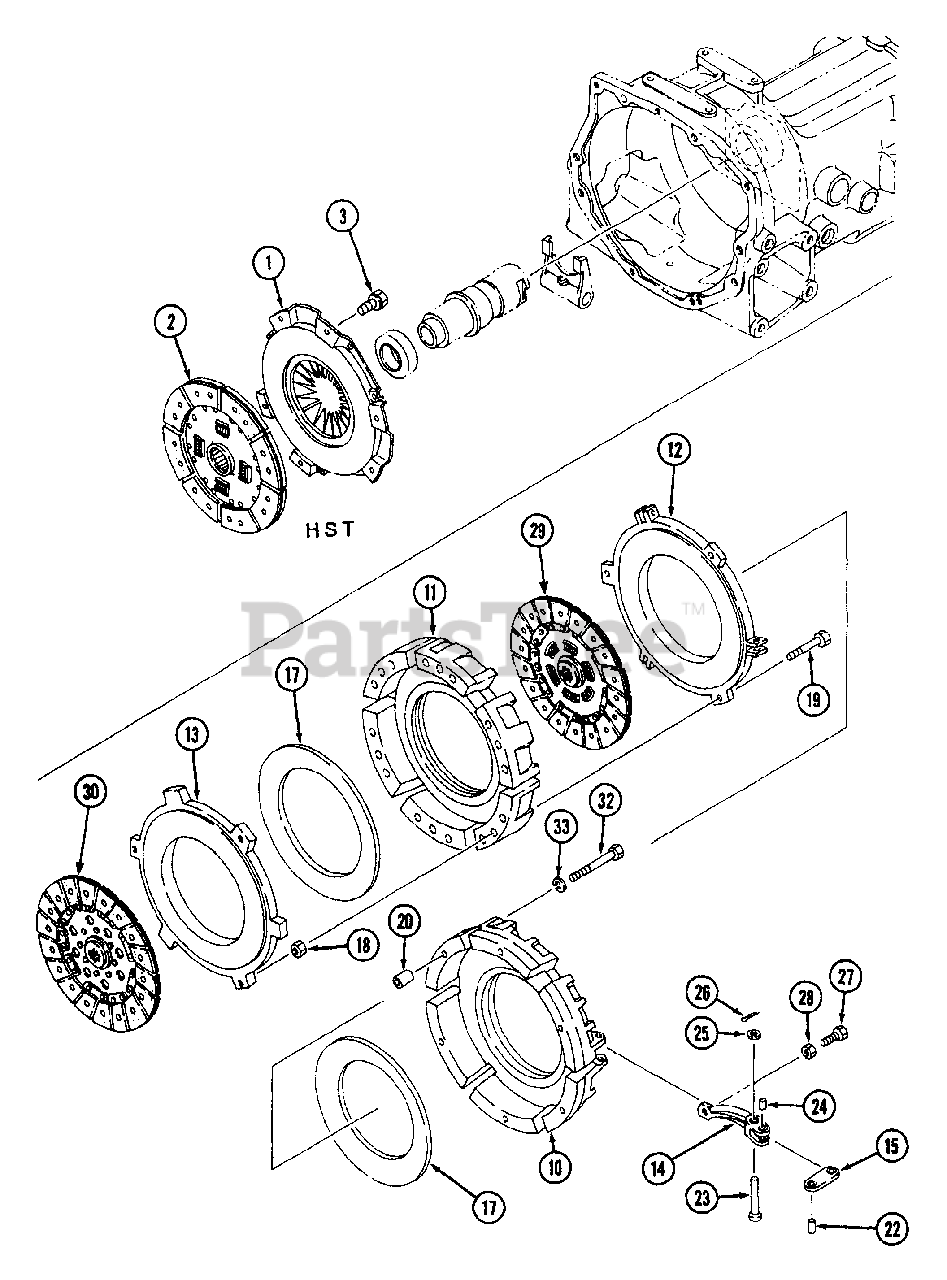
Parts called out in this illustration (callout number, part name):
1	Cover Ass'y. (HST)
2	Disk Ass'y. (HST)
3	Bolt (HST)
10	Clutch Cover (Gear)
11	Clutch Cover (Gear)
12	Pressure Plate (Gear)
13	Pressure Plate (Gear)
14	Release Lever Sub Ass'y. (Gear)
15	Release Rod Sub Ass'y. (Gear)
17	Diaphragm Spring (Gear)
20	Knock Pin (Gear)
25	Washer (Gear)
26	Pin, Split (Gear)
27	Adjust Bolt (Gear)
29	Clutch Disc Ass'y. (Gear)
30	Clutch Disc Ass'y. (Gear)
33	Washer (Gear)
